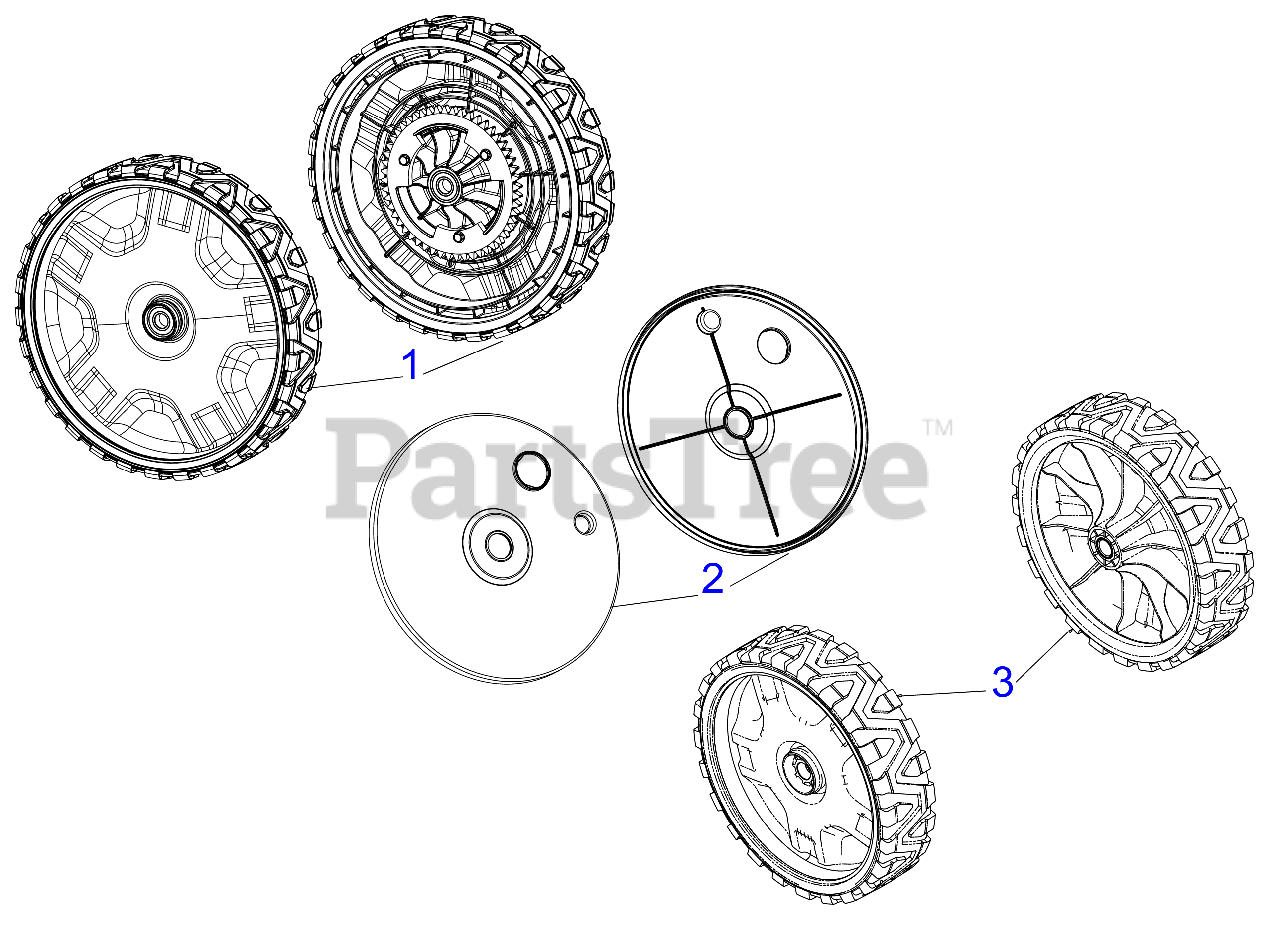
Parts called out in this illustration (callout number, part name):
1	WHEEL ASSEMBLY 11X2 (BLACK)
2	DUST COVER 11"
3	WHEEL ASSEMBLY (8 x 2)
